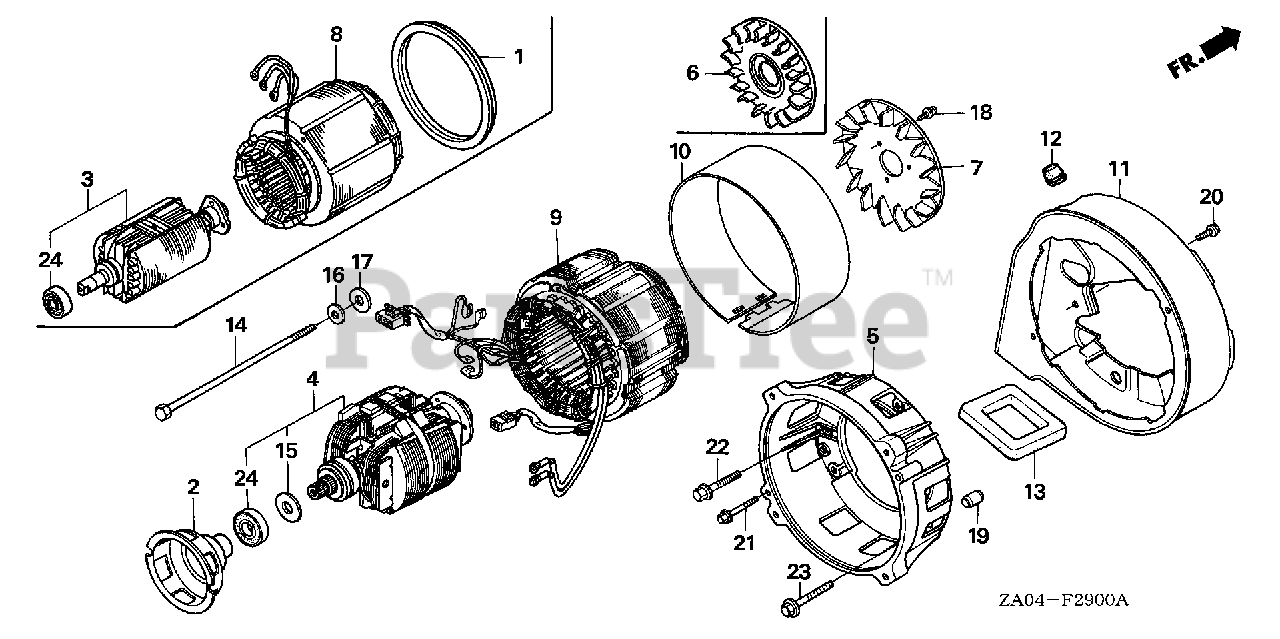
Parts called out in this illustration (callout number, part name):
4	ROTOR
9	STATOR (NOT AVAILABLE)
10	COVER, STATOR *NH116M* (URBAN SILVER METALLIC)
14	BOLT, HEX. (10X300)
15	WASHER, THRUST
16	WASHER, PLAIN (10MM)
18	SCREW, TAPPING (5X14)
24	BEARING ASSY. (6205)
